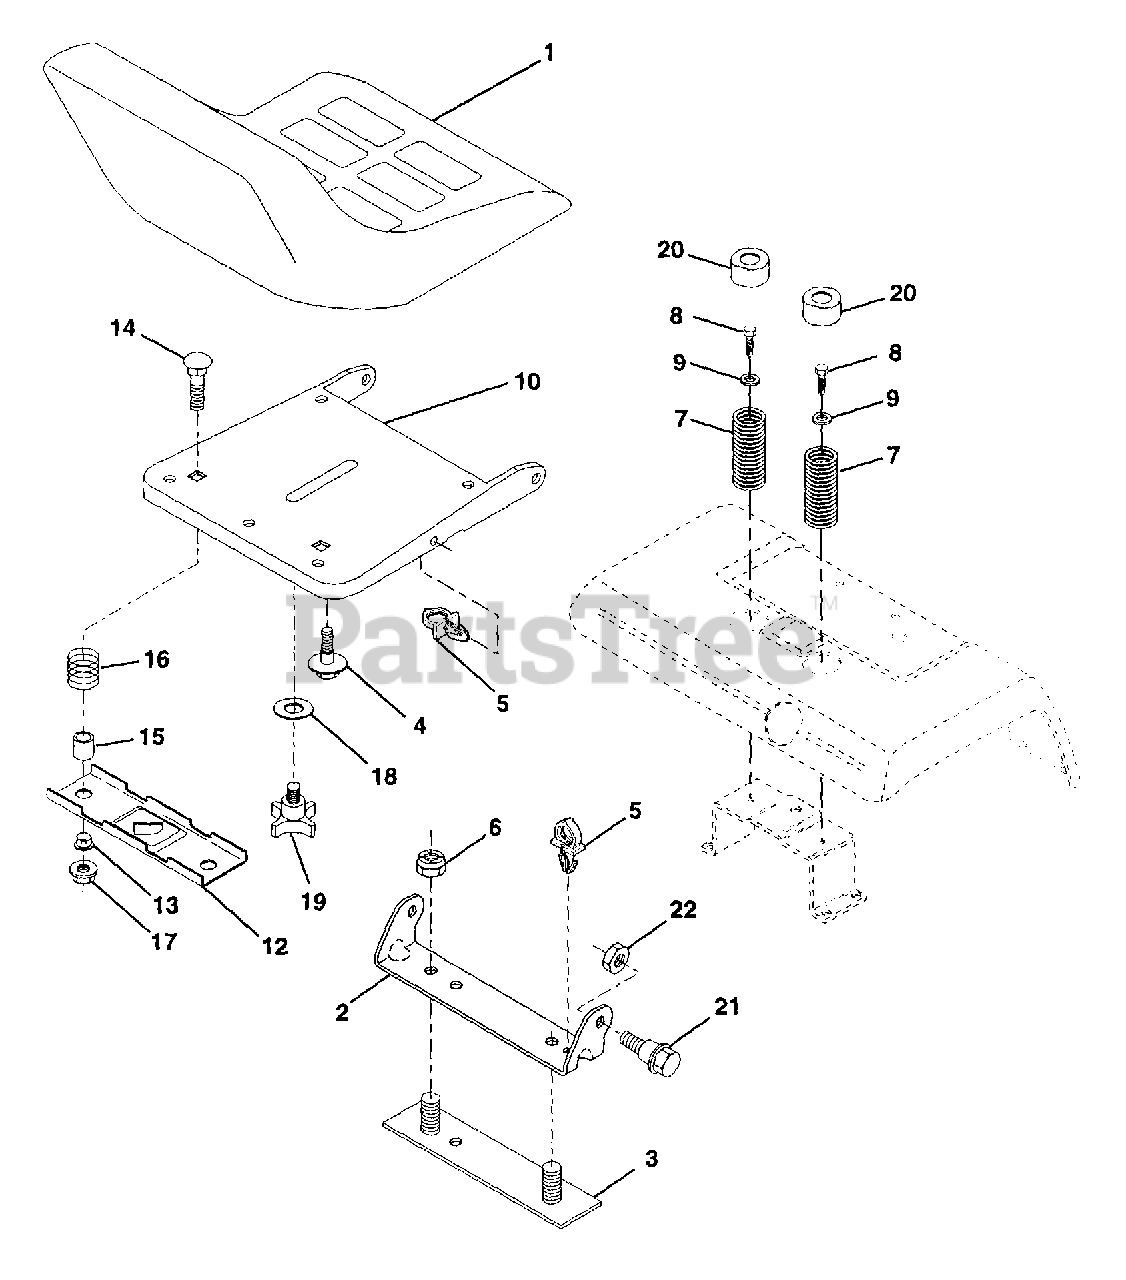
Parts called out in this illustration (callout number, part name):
1	Seat
2	Bracket, Pivot Seat
3	Strap, Fender
4	Bolt, Shoulder 5/16-18 X .62
5	Clip, Push In Hinged
6	Locknut 3/8-16 Unc
7	Spring, Seat Cprsn
8	Screw, Thdrol 5/16-18 X 1/2
9	Washer 13/32 X 1 X 14 Ga.
10	Pan, Seat
12	Bracket, Mounting Switch
13	Bushing, Snap
14	Bolt, Carriage 1/4-20 X 1-3/8
15	Spacer, Split
16	Spring, Cprsn
17	Nut, Lock 1/4 Lge Flg Gr. 5
18	Washer 17/32 X 1-3/16 X 12 Ga.
19	Knob, Seat 1/2-13 Unc
20	Cap, Spring Seat
21	Bolt, Shoulder 5/16-18 Unc
22	Nut, Crownlock 5/16-18 Unc
